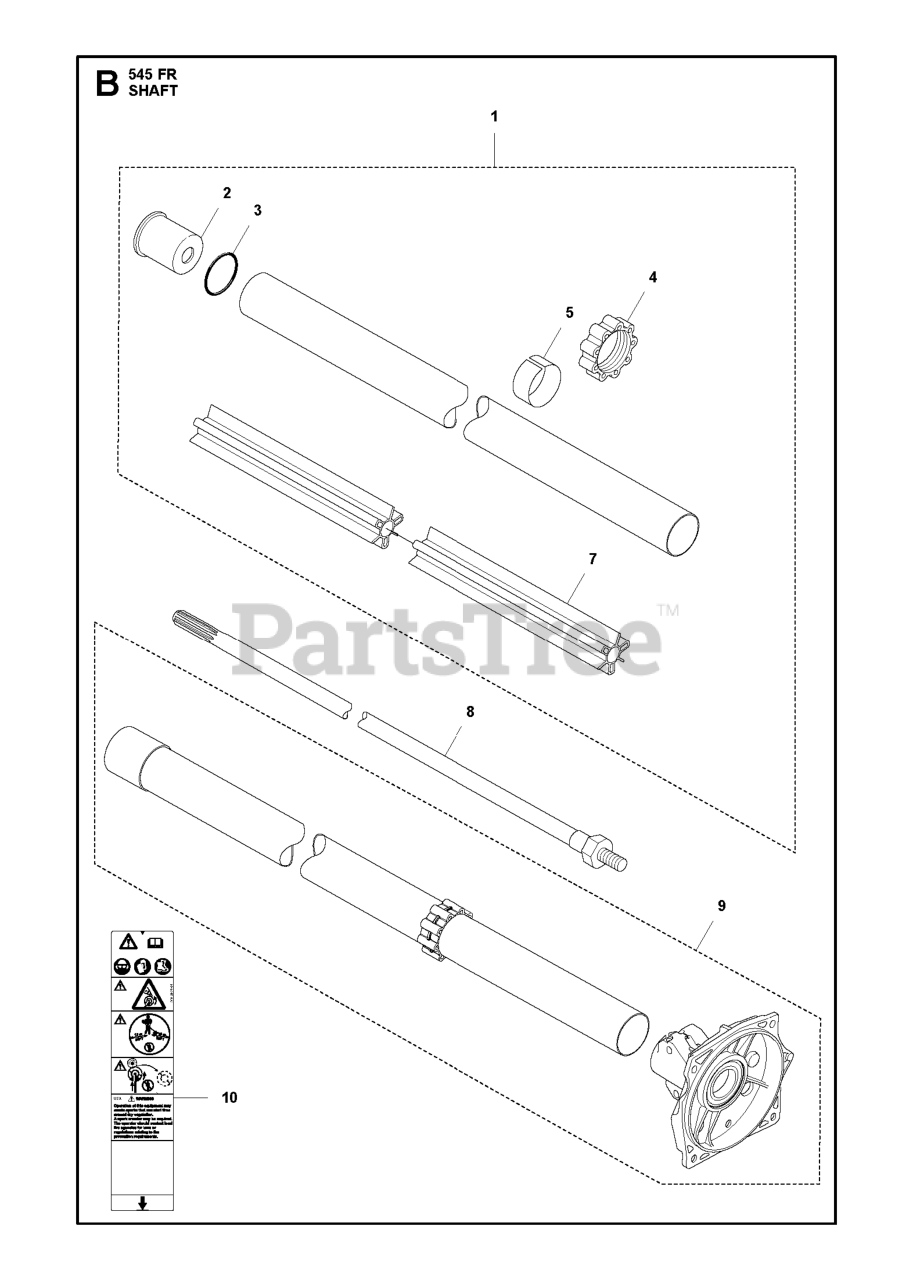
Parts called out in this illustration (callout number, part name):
1	Tubes
2	SPACER SLEEVE
4	MOVEMENT LIMITER
5	%BAND
7	BEARING SHAFT
8	DRIVE SHAFT
9	Covers
10	LABEL WARNING TRIMMERS AND BRU
